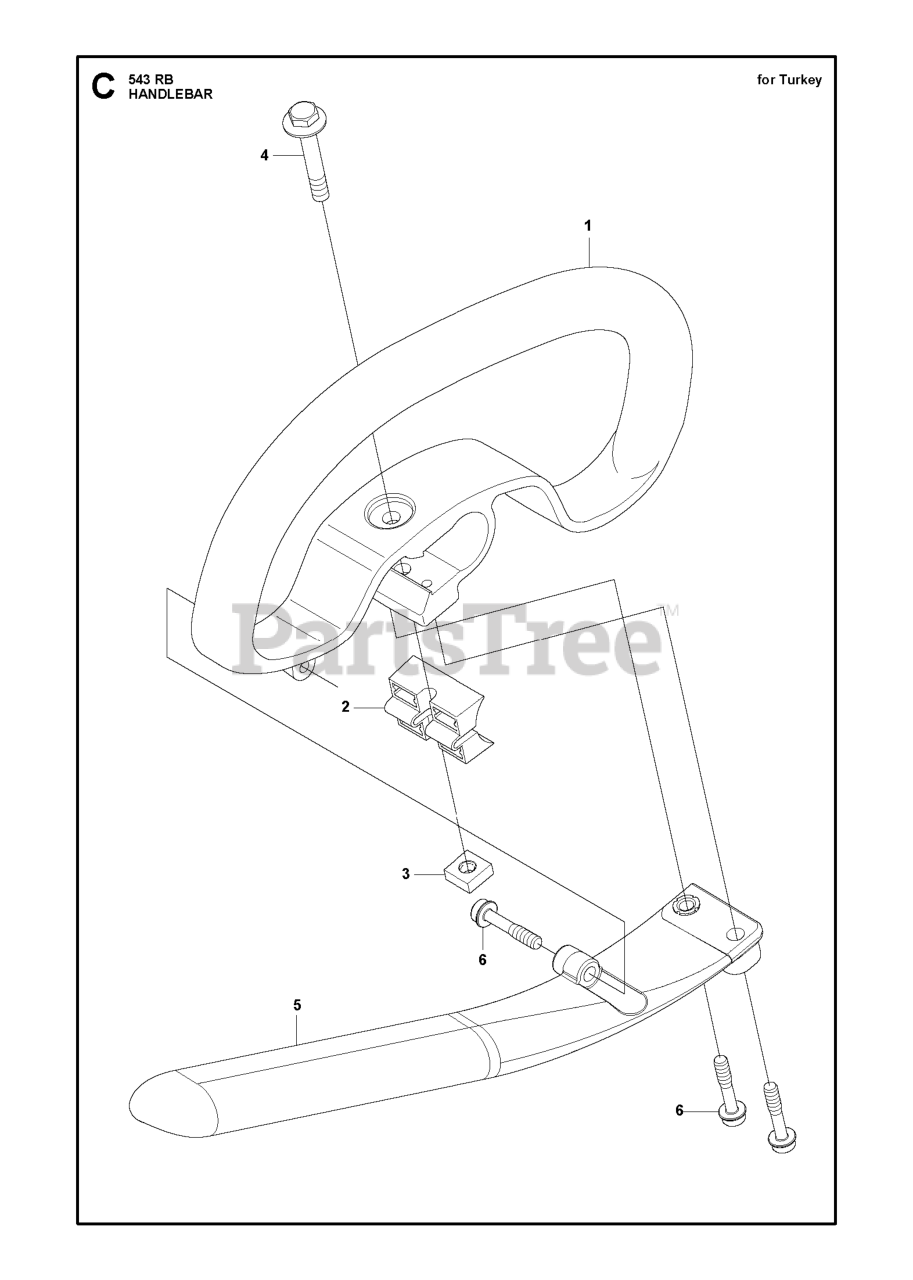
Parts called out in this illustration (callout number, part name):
1	HANDLE.LOOP
2	SPACER
3	NUT
5	HANDLE
6	SCREW IHSCFTO
